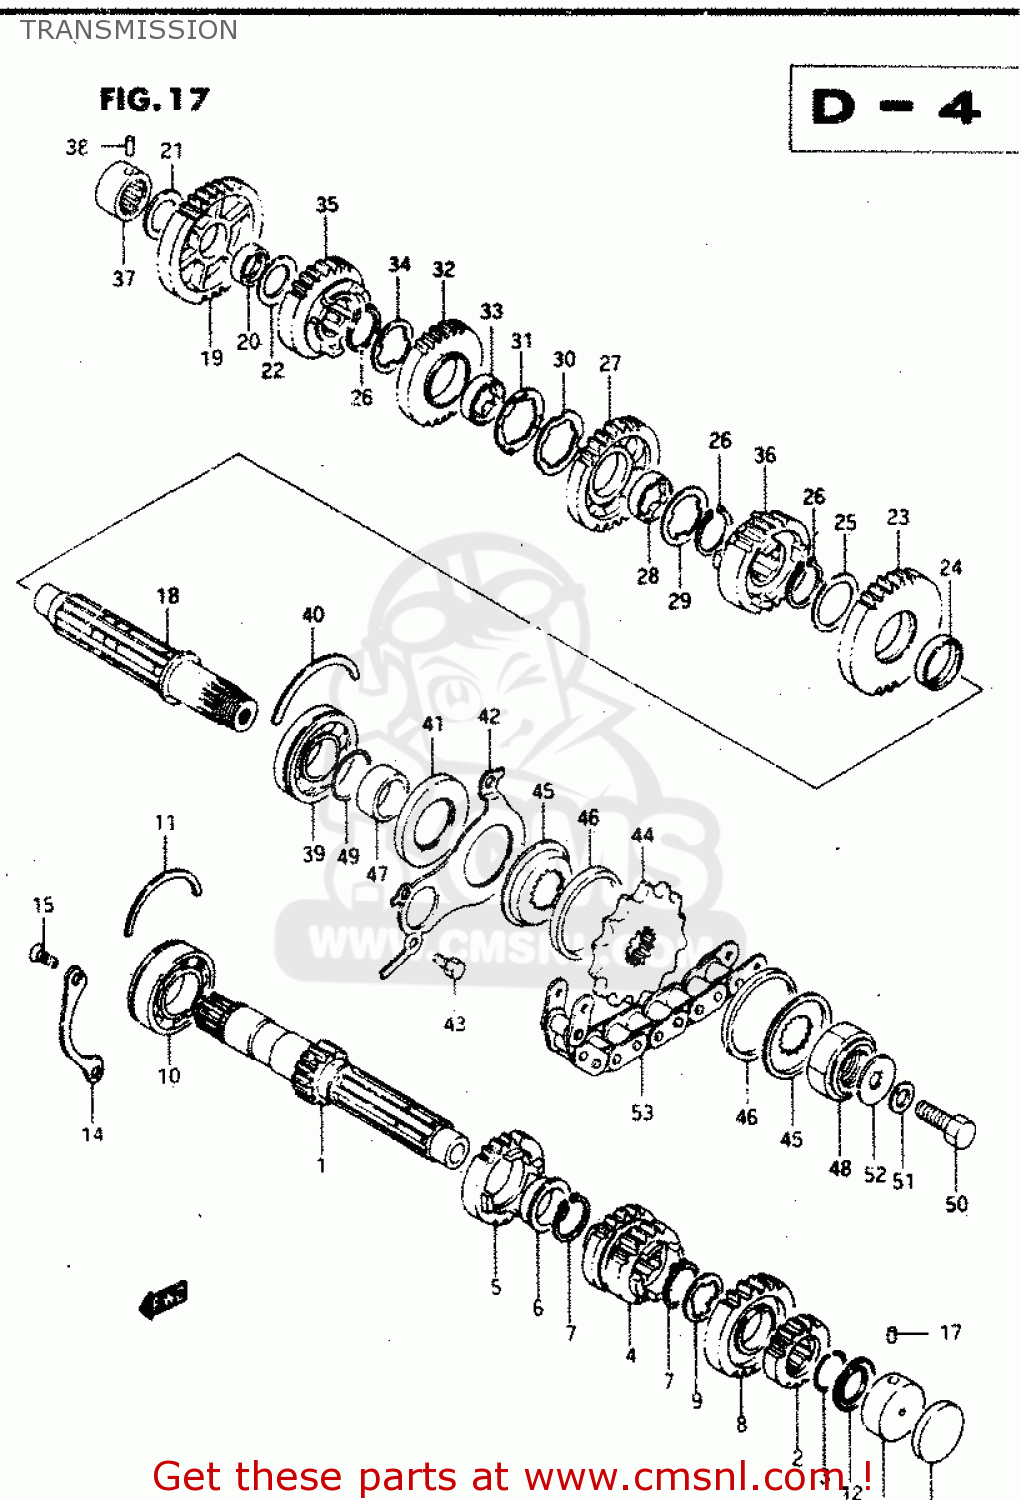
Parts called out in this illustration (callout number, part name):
1	SHAFT,COUNTER
2	GEAR,2ND DRIVE(NT:16)
3	RING,SNAP
4	GEAR,3RD & 4TH DRIVE(NT:17/20)
5	GEAR,5TH DRIVE(NT:22)
6	BUSHING
7	RING,SNAP
8	GEAR,SIXTH DRIVE
9	WASHER,LOCK
10	BEARING(25X62X17)
11	C-RING
12	SEAL,OIL(20X31.2X2.7)
13	CAP,COUNTER SHAFT,L
14	RETAINER,CNTR SHAFT BEARING
15	SCREW
16	BEARING(20X34X17.5)
17	PIN
18	SHAFT,DRIVE
19	GEAR,1ST DRIVEN(NT:36)
20	BUSH(22X26X9)
21	WASHER
22	WASHER
23	GEAR,SECOND DRIVEN
24	BUSH(28X32X8)
25	WASHER, THRUST
26	CIRCLIP
27	GEAR,3RD DRIVEN(NT:28)
28	BUSH
29	WASHER,LOCK
30	WASHER,LOCK
31	WASHER
32	GEAR,FOURTH DRIVEN
33	BUSH
34	WASHER,LOCK
35	GEAR,5TH DRIVEN(NT:27)
36	GEAR,SIXTH DRIVEN
37	BEARING(20X34X20)
38	PIN
39	BALL BEARING 25X62X17
40	C-RING
41	SEAL,OIL(34X62X6)
42	RETAINER,DRIVESHAFT O
43	BOLT
44	SPROCKET,ENGINE
45	HOLDER,SPROCKET DAMPER
46	DAMPER,SPROCKET
47	SPACER (25X34X16.1)
48	NUT
49	O RING(D:1,ID:24.5)
50	BOLT
51	WASHER,LOCK
52	WASHER
53	CHAIN ASSEMBLY,DRIVE
